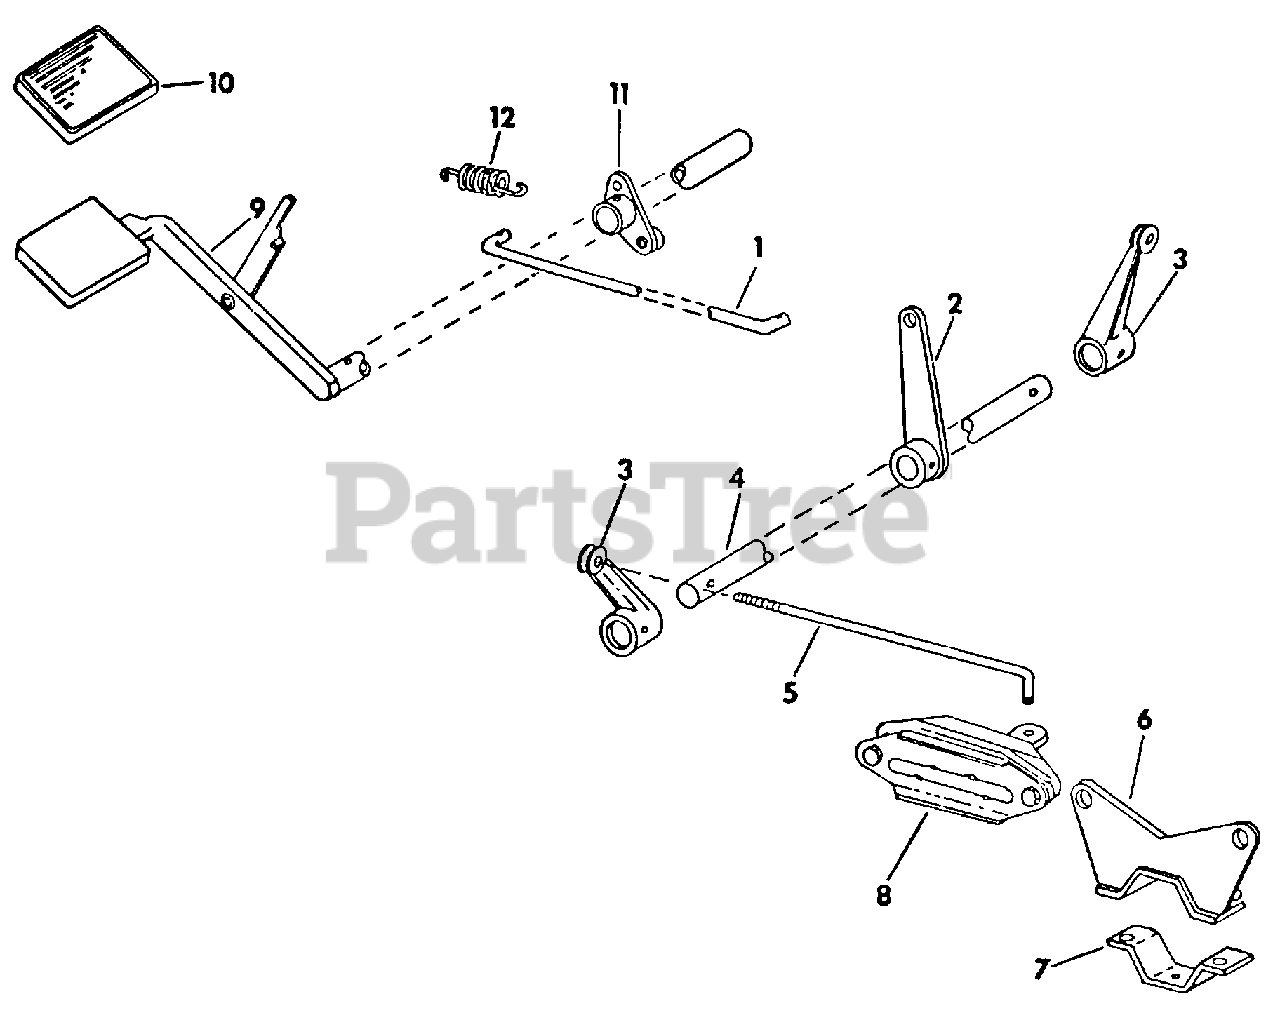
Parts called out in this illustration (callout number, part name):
1	Rod, Brake
2	Lever Assy, Brake
4	Shaft, Brake Pivot
6	Bracket Assy, Caliper
7	Flange, Caliper Mounting
8	Caliper Assy, Brake RH
9	Pedal Assy, Clutch
10	Pad, Pedal
11	Lever Assy, Clutch & Brake
12	Spring, Brake Pedal Return
